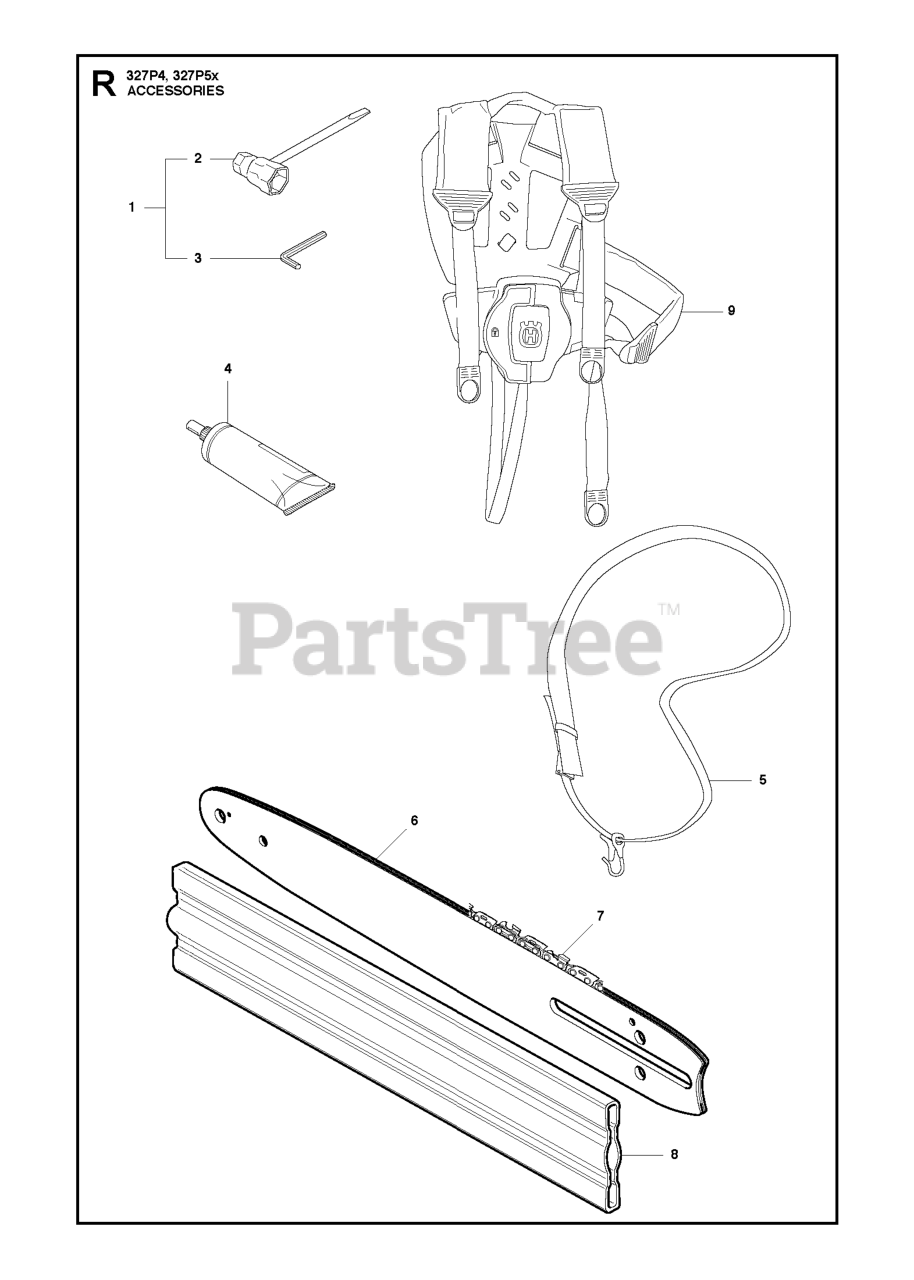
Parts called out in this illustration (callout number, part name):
1	ACCESSORY KIT
2	COMBI TOOL
3	L-KEY WRENCH
4	BEVEL GEAR GREASE
5	Harness-w/o warning
6	Hl280-45 Guide Bar
6	Hl280-40 Guide Bar
7	RP12" CHN,H37-45 3/8,.050 MINI
7	10" CHN, H37-40 3/8,.050 MINI
9	RP BALANCE FLEX HARNESS
